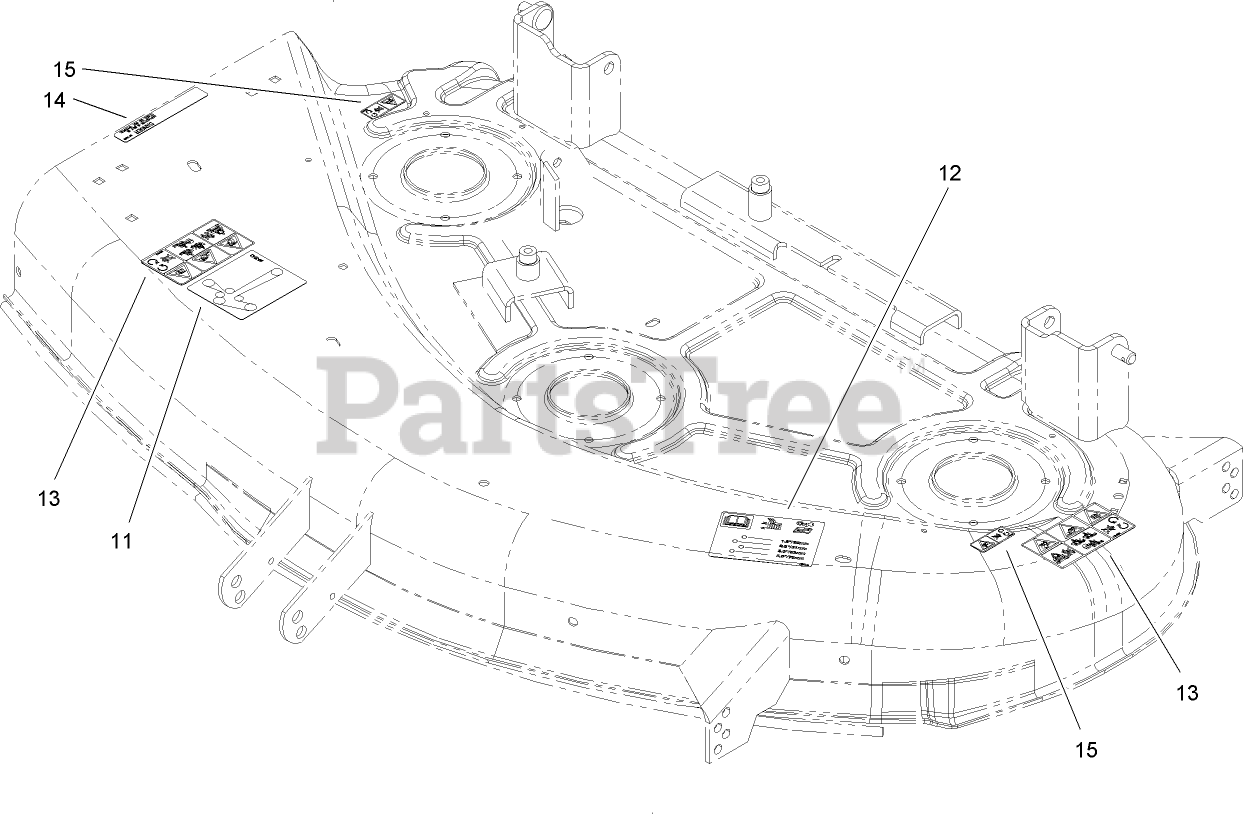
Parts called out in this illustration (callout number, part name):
11	DECAL-ROUTING, BELT
12	DECAL-SCALP, ANTI
13	DECAL-DANGER
14	DECAL-DANGER
15	DECAL-DANGER
